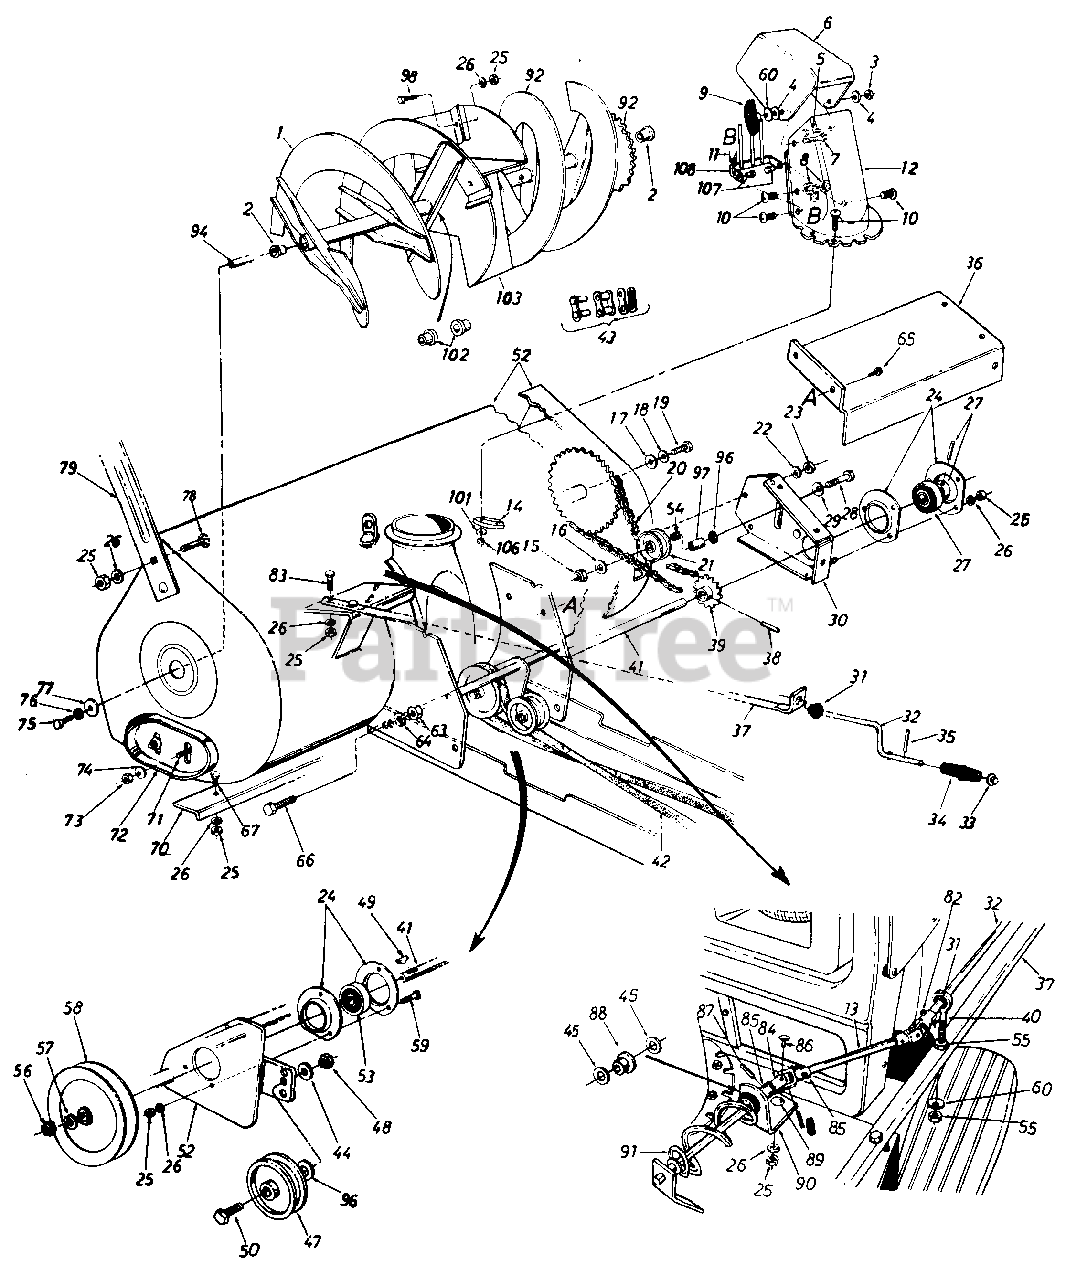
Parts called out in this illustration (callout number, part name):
3	Hex Cent. L.-Nut 5/16-18 Thd.
4	Fl.-Wash. .344' I.D.
5	Truss Mach. Scr. 5/16-18 x .75" Lg.
6	Upper Chute
7	Carriage Bolt 5/16-18 x 1.0" Lg.
8	Hex L-Nut 1/4-20 Thd.
9	Hanc Knob
10	Truss Mach. Scr. 1/4-20 x .75" Lg.
11	Ext. Spring
12	Lower Chute
13	Chute Crank Extension Rod
14	Chute Flange Keeper
15	L.-Nut 3/8-16 Thd.
16	Fl.-Wash.
17	Fl.-Wash.
18	Belleville Wash.
19	Hex Bolt 1/2-13 x 1.00" Lg.*
20	#420 Chain 1/2" Pitch x 77 Links
21	Plastic Idler 2.00" O.D.
22	L.-Wash. 1/4" I.D.*
23	Hex Nut 1/4-20 Thd.*
24	Bearing Housing
25	Hex Nut 5/16-18 Thd.*
26	L.-Wash. 5/16" I.D.*
27	Self-Aligning Bearing
28	Hex Bolt 3/8-16 x 1.75" Lg.*
29	Belleville Wash. 3/8" I.D.
32	Chute Crank .375 Dia. x 34.5" Lg.
33	Push Nut 3/8" Rod
34	Knob Black
35	Roll Pin
39	14 Teeth Sprocket Ass'y.
40	Eyebolt 5/16-18 x 3.0" 4.
41	Drive Shaft
42	"V"-Belt
43	Master Link for #420 Chain
44	L.-Wash. 3/8" I.D.
45	Fl.-Wash..385 I.D. x .62" O.D.
47	Fl.-ldler with Flanges
48	Hex Jam L.-Nut 3/8-16 Thd.
49	#61 Hi-Pro Key 3/16 x 5/8 Dia.
50	Hex Bolt 3/8-16 x 1.75" 4.*
52	Spiral Housing Ass'y.
53	Self-Aligning Bearing
54	Sleeve Bearing .50" I.D.
55	Hex Nut 5/16-18 Thd.*
56	Hex Nut 3/4-10 Thd.
57	L.-Wash. 3/4" I.D.
58	"V"-Pulley .750" I.D. x 6.00" O.D.
59	Hex Sems Bolt 5/16-18 x .75" 4.*
60	Bell.-Wash. .345" I.D. x .88" O.D.
63	Hex Nut 1/2-13 Thd.*
64	L.Wash. 1/2" I.D.*
65	Hex Wash. Hd. Tap Scr. 1/4-20 x .50" 4.
66	Hex Bolt 1/2-13 x 2.75" Lg.
67	Carriage Bolt 5/16-18 x .75"*
72	Skid Shoe
73	Hex Jam Nut 3/8-16 Thd.
74	Belleville Wash. 3/8" I.D.
75	Hex Bolt 1/2-13 x 1.00" Lg.*
76	Belleville Wash. 1/2" I.D.
77	Fl.-Wash.
78	Carriage Bolt 5/16-19 x .62" Lg.*
82	Cotter Pin
83	Hex Bolt 5/16-18 x 1.50" Lg.*
84	Joint Block
85	Joint Bracket Ass'y.
86	Oval Head Rivet
87	Spring Pin Roll 1/8" Dia. x .75" Lg.*
88	Nylon Bushing
89	Carriage Bolt 5/16-18 x .75" Lg.
90	Chute Crank Bracket
91	Chute Crank Ass'y.
96	Flat Washer
97	Idler Spacer
98	Carriage Bolt 5/16-18 x .75" Lg.
101	Fl.-Wash. 1/4" I.D.
102	Plastic Bushing
107	Shld. Nut 1/4-20 Thd.
